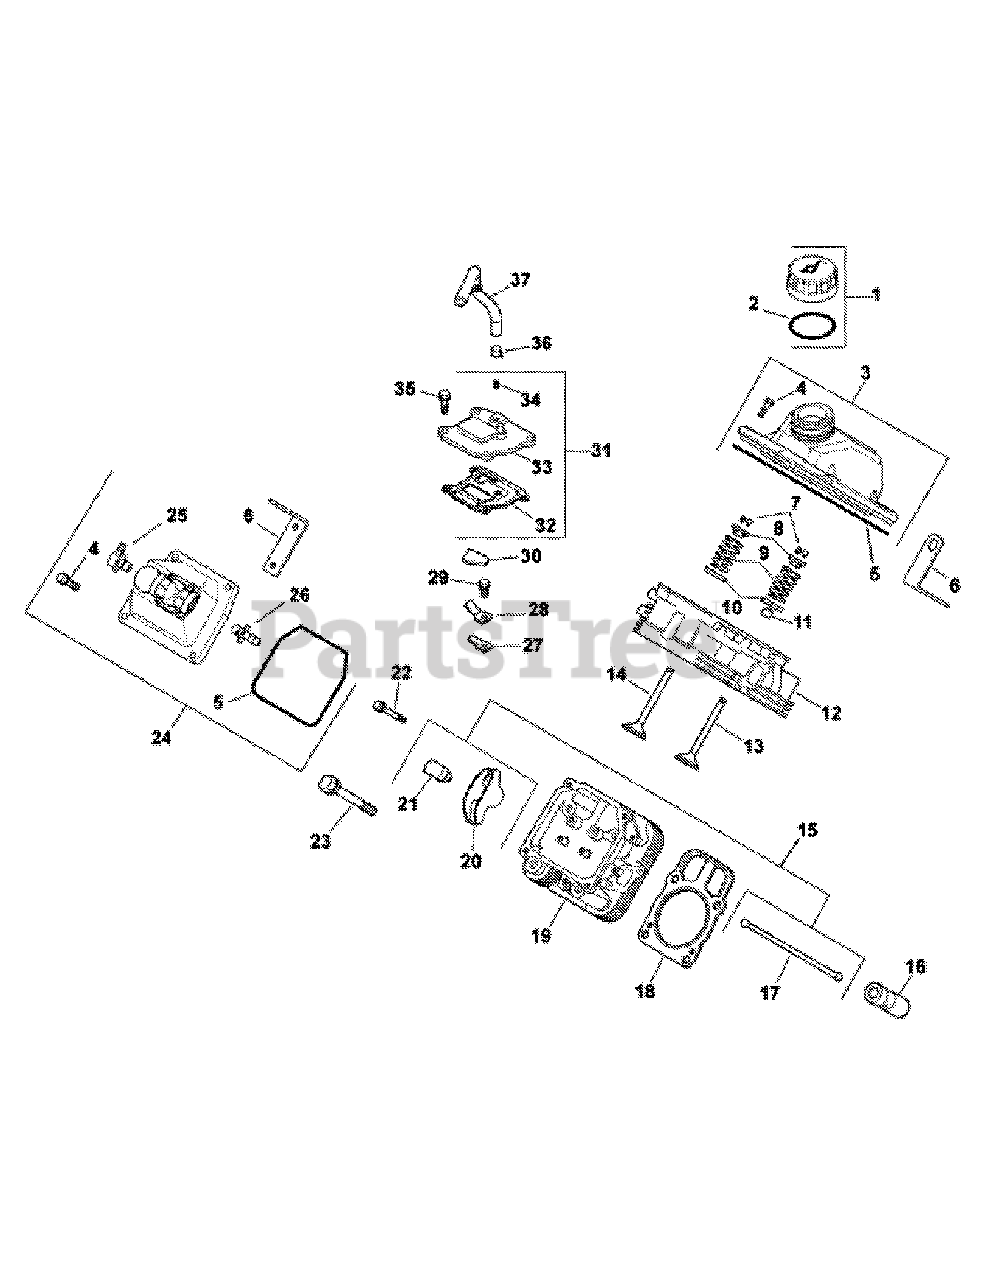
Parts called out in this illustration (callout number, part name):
1	Kit, Oil Fill Cap (Yellow) (Includes 2)
2	O-Ring, Dipstick
3	Kit, Valve Cover-Oil Fill (Includes 4,5)
4	Screw, Flg M6X1.0X30
5	O-Ring, Valve Cover Use 24 153 30-S
6	Strap, Lifting Use 25 445 01-S
7	Kit, Retainer
8	Cap, Valve Spring - Use 25 173 28-S
9	Spring, Valve
10	Retainer, Spring
11	Seal, Valve Stem
12	Kit, #1 Cylinder Head Assembly
13	Valve, Intake (Std)
13	Valve, Intake (.25)
14	Valve, Exhaust (Std)
14	Valve, Exhaust (.25)
15	Kit, Valve Train (Includes 17,20,21)
16	Kit, Hydraulic Valve Lifter
18	Kit, Cyl Head Gasket (C17-22)
19	Kit, #2 Cylinder Head Assembly
21	Pivot, Rocker Arm
22	Screw, Flg M6X1.0X34
23	Screw, Flg M10X1.5X90
24	Kit, Valve Cover-Fuel Pump (Includes 4,5,25)
25	Kit, 90 degree Fitting
26	Kit, 1/4" Fitting (Straight)
27	Reed, Breather
28	Retainer, Reed
29	Screw, Flg Thd Frm M5X.8X10
30	Filter, Breather Use 24 050 11-S
31	Kit, Breather Assembly
32	Gasket, Breather Use 24 041 64-S
33	Kit, Breather Cover Use 24 033 01-S
34	Plug, Ctsk Pipe 1/8"
35	Screw, Flg Thd Frm M6X1.0X20
36	Clamp, Hose 1/2"
37	Breather Hose
